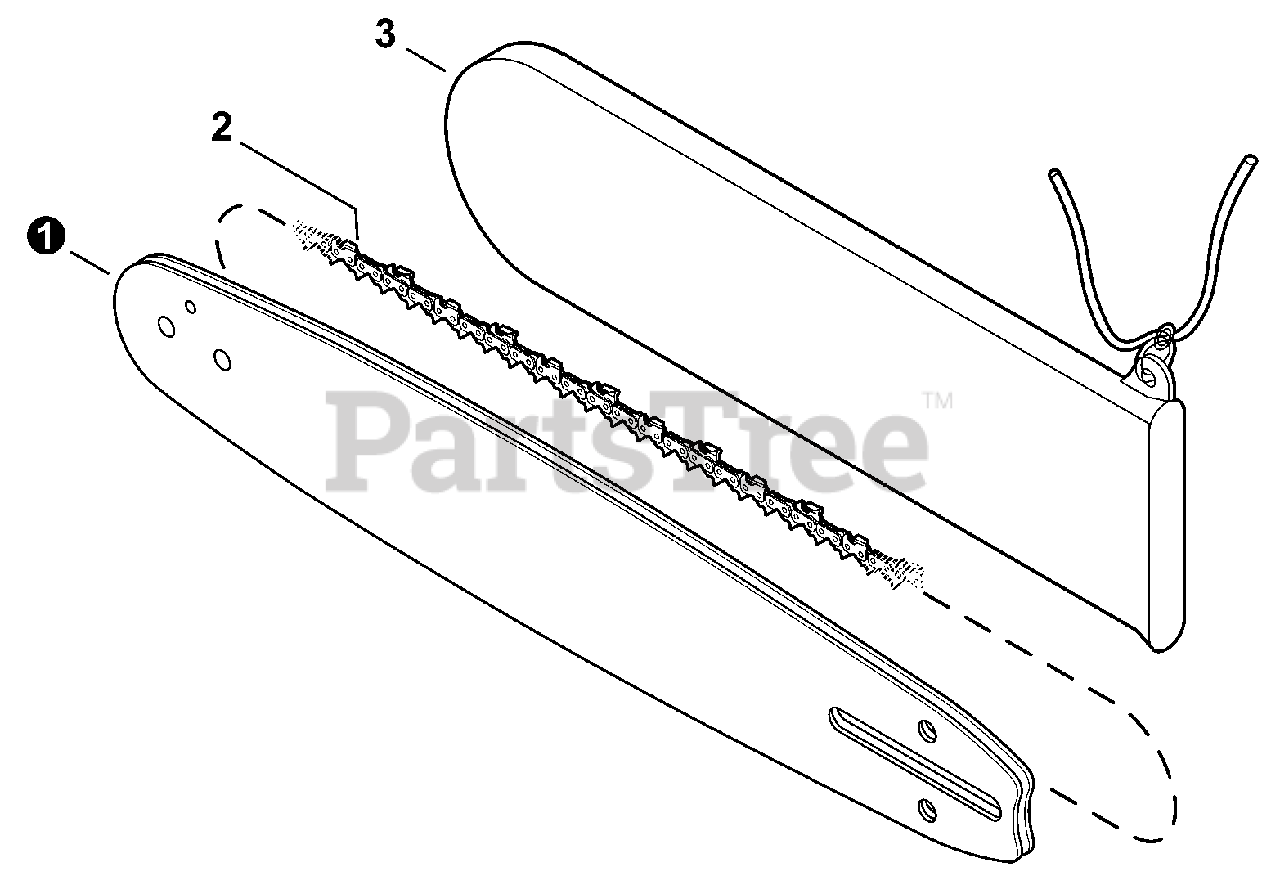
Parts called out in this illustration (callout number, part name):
1	GUIDE BAR, 24"
2	SAW CHAIN 24"
3	SCABBARD
